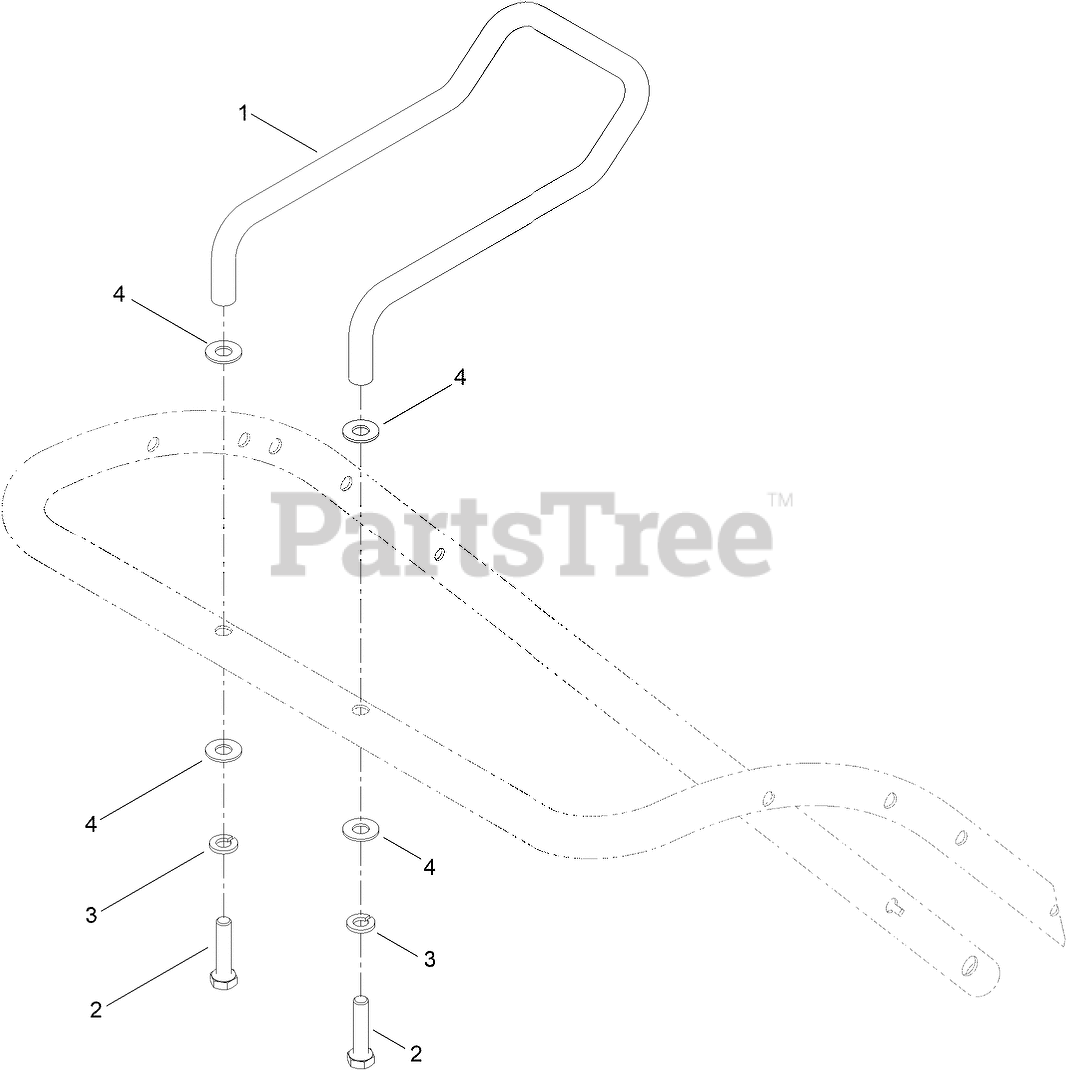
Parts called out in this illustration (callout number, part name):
1	HANDLE-ASSIST, STEEL
2	SCREW-HH
3	WASHER-LOCK
4	WASHER
